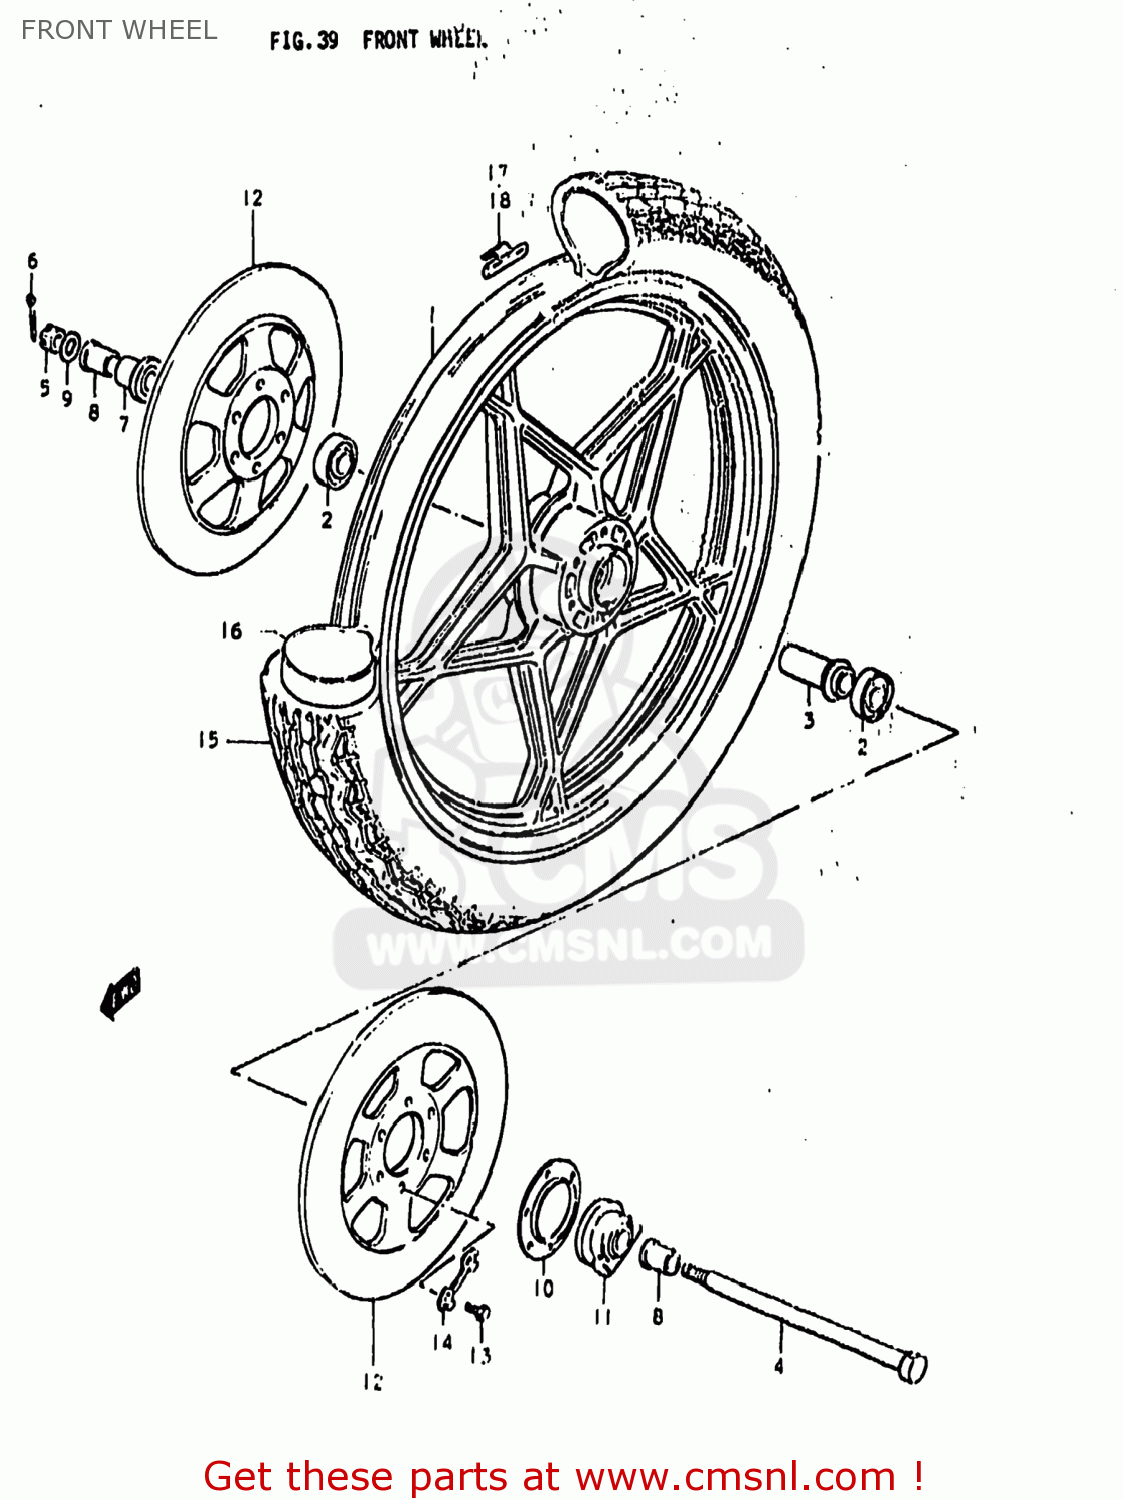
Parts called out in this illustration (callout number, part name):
1	CASTING WHEEL,FRONT
2	BEARING
3	SPACER,FR HUB BEARING
4	AXLE,FR
5	NUT 12MM
6	COTTER PIN
7	SPACER,FR AXLE,R
8	SPACER,FR AXLE,L
9	WASHER
10	DUST SEAL,SPEEDOMETER GEAR BOX
11	BOX ASSEMBLY,SPEEDOMETER GEAR
12	DISC,REAR BRAKE
13	BOLT(8X25)
14	WASHER
15	TIRE,FRONT
16	TUBE,INNER
17	BALANCER,WHEEL
18	BALANCER,WHEEL
